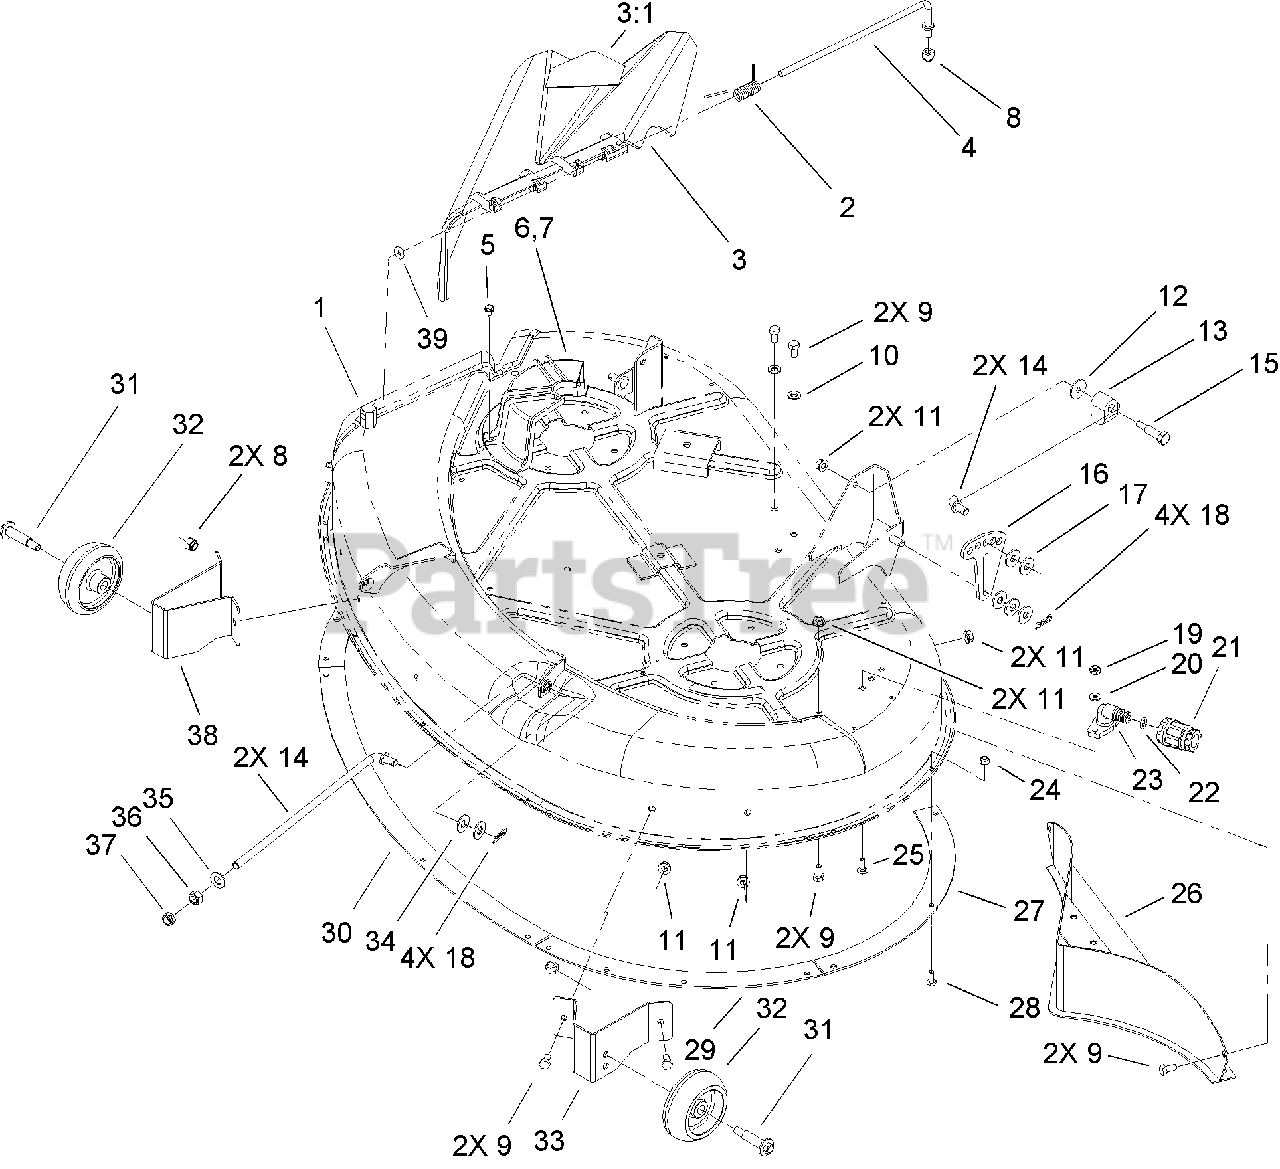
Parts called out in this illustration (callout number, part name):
1	42IN DECK ASM
3	DEFLECTOR ASM
3:1	DECAL-DANGER
4	ROD-PIVOT
7	RH BELT GUIDE-DECK
8	NUT-LOCK, NI
9	SCREW-HH
10	WASHER-FLAT
12	WASHER-PIVOT
13	TRUNNION-HOC
14	ROD-HANGER
15	BOLT-SHOULDER
16	LINK-ADJUSTING, HOC
17	WASHER-HARDENED
18	PIN-HAIR
19	NUT-LOCK, NI
20	WASHER-FLAT
21	CONNECTOR-HOSE
23	FITTING-WASHOUT
24	NUT-LOCK, NI
25	SCREW-CARR
26	REAR BAFFLE ASM
27	RING-BLOW OUT, SIDE
28	SCREW-HH
29	RING-BLOW OUT, SIDE
30	RING-BLOW OUT
31	BOLT-WHEEL
32	WHEEL-GAGE
33	BRACKET-GAGE WHEEL, FRONT (LH)
34	WASHER-FLAT
35	WASHER-FLAT
36	NUT-HEX
37	NUT-LOCK, NI
38	BRACKET-GAGE WHEEL, FRONT (RH)
